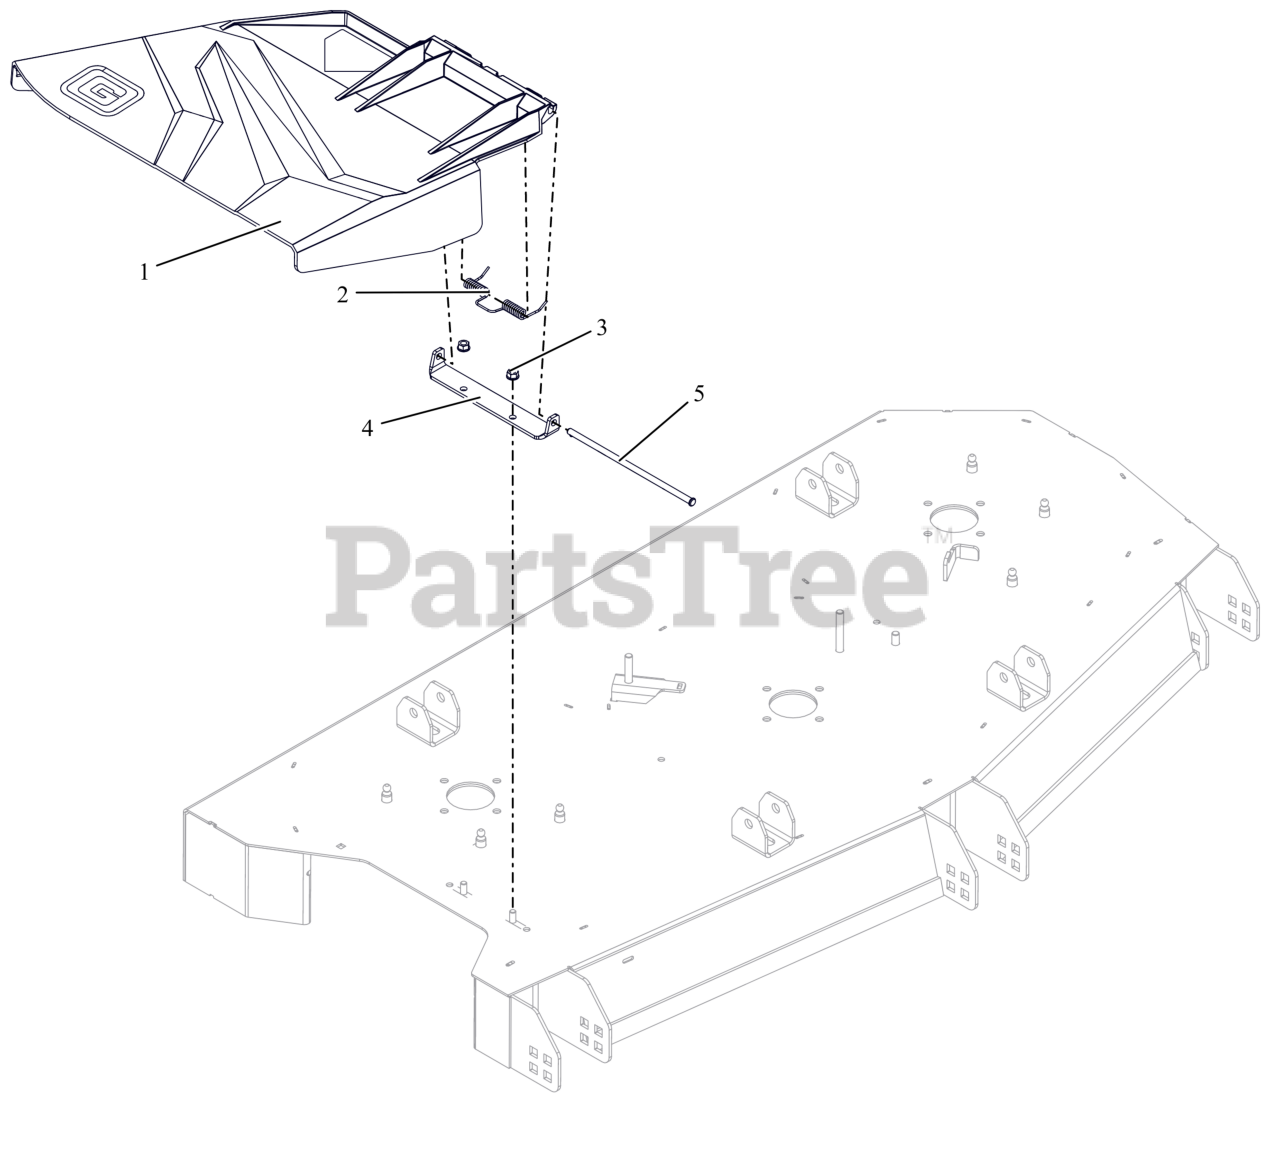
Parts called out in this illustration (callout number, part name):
1	CHUTE- SIDE DISCHARGE
2	SPRING-TORSION
3	NUT,LK-CTR-FLG .31-18 GF ZCC
4	BRKT- DISCHARGE CHUTE-GRAVELY
5	PIN, SLIC-.312X10.45
